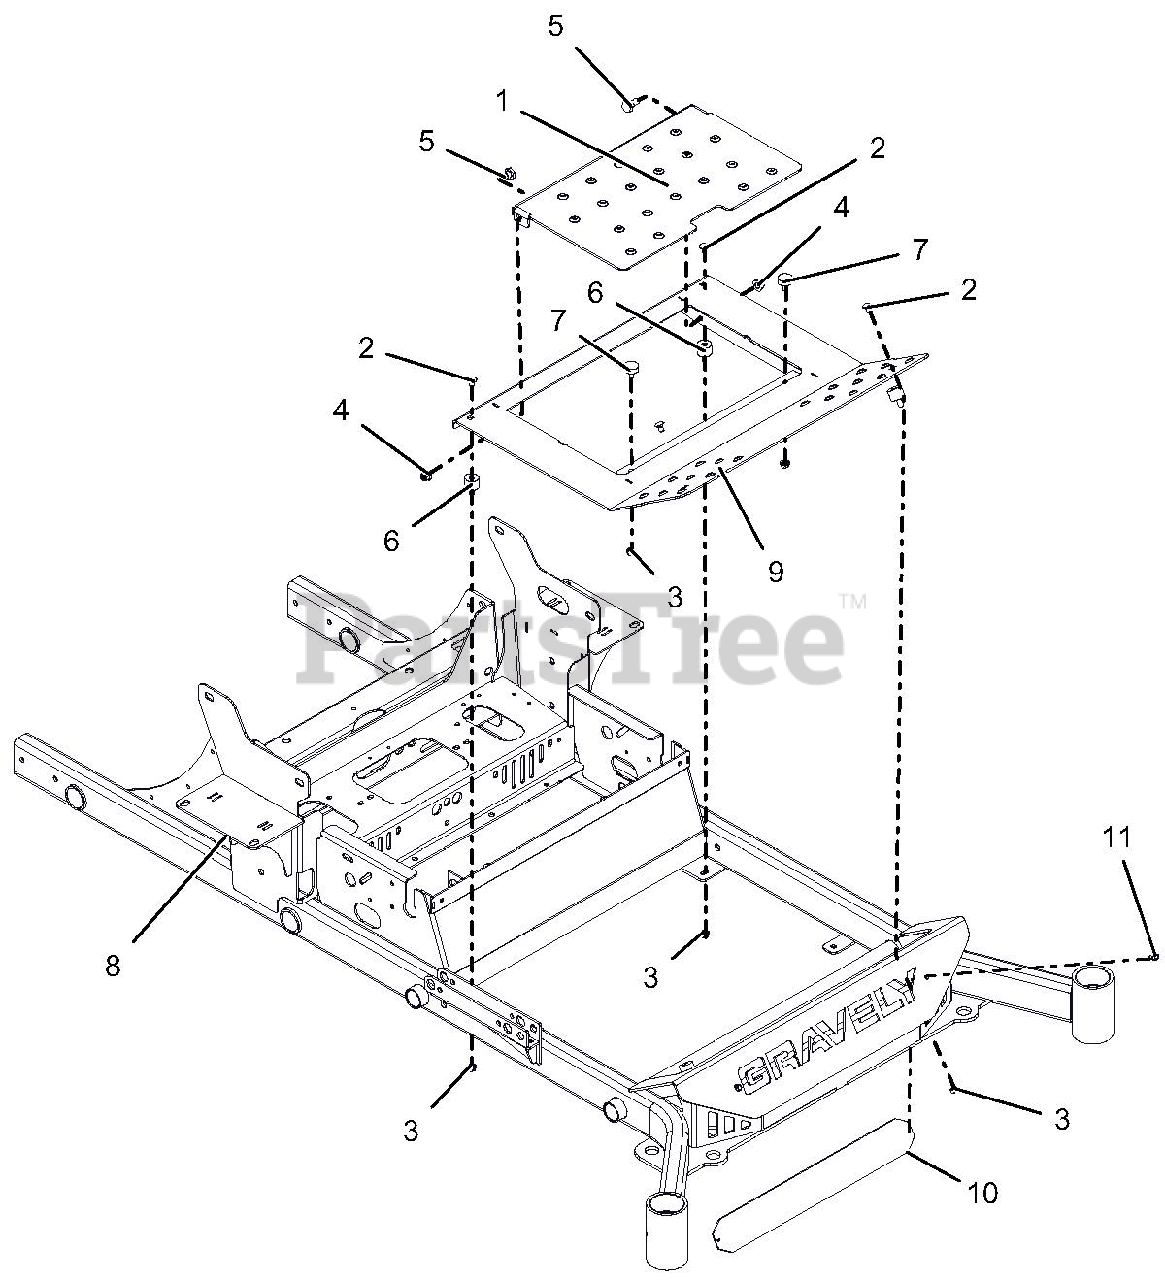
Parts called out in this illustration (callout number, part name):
1	PANEL, INSPECTION
2	BLT-RDHDSQNK .31-18X.50 G5 YWZC
3	@NUT-SPNLK-FLG .312-18 YWZC
4	NUT-LK-NYL-FLG .38-16 YWZC
5	BLT, SHLDR EP .38-16X.30 HEX YZ
6	BUMPER, STUD MOUNTED W/FEMALE INSERT
7	BUMPER, RUBBER
8	52-66" MAIN FRAME W/SAFETY DECALS
9	FOOTPLATE WLDMT W/SAFETY DECAL
10	PLATE, BUMPER LOGO BACKING-BLACK
11	SCR-TAP .25-20X.50 HWH TR YWZ
